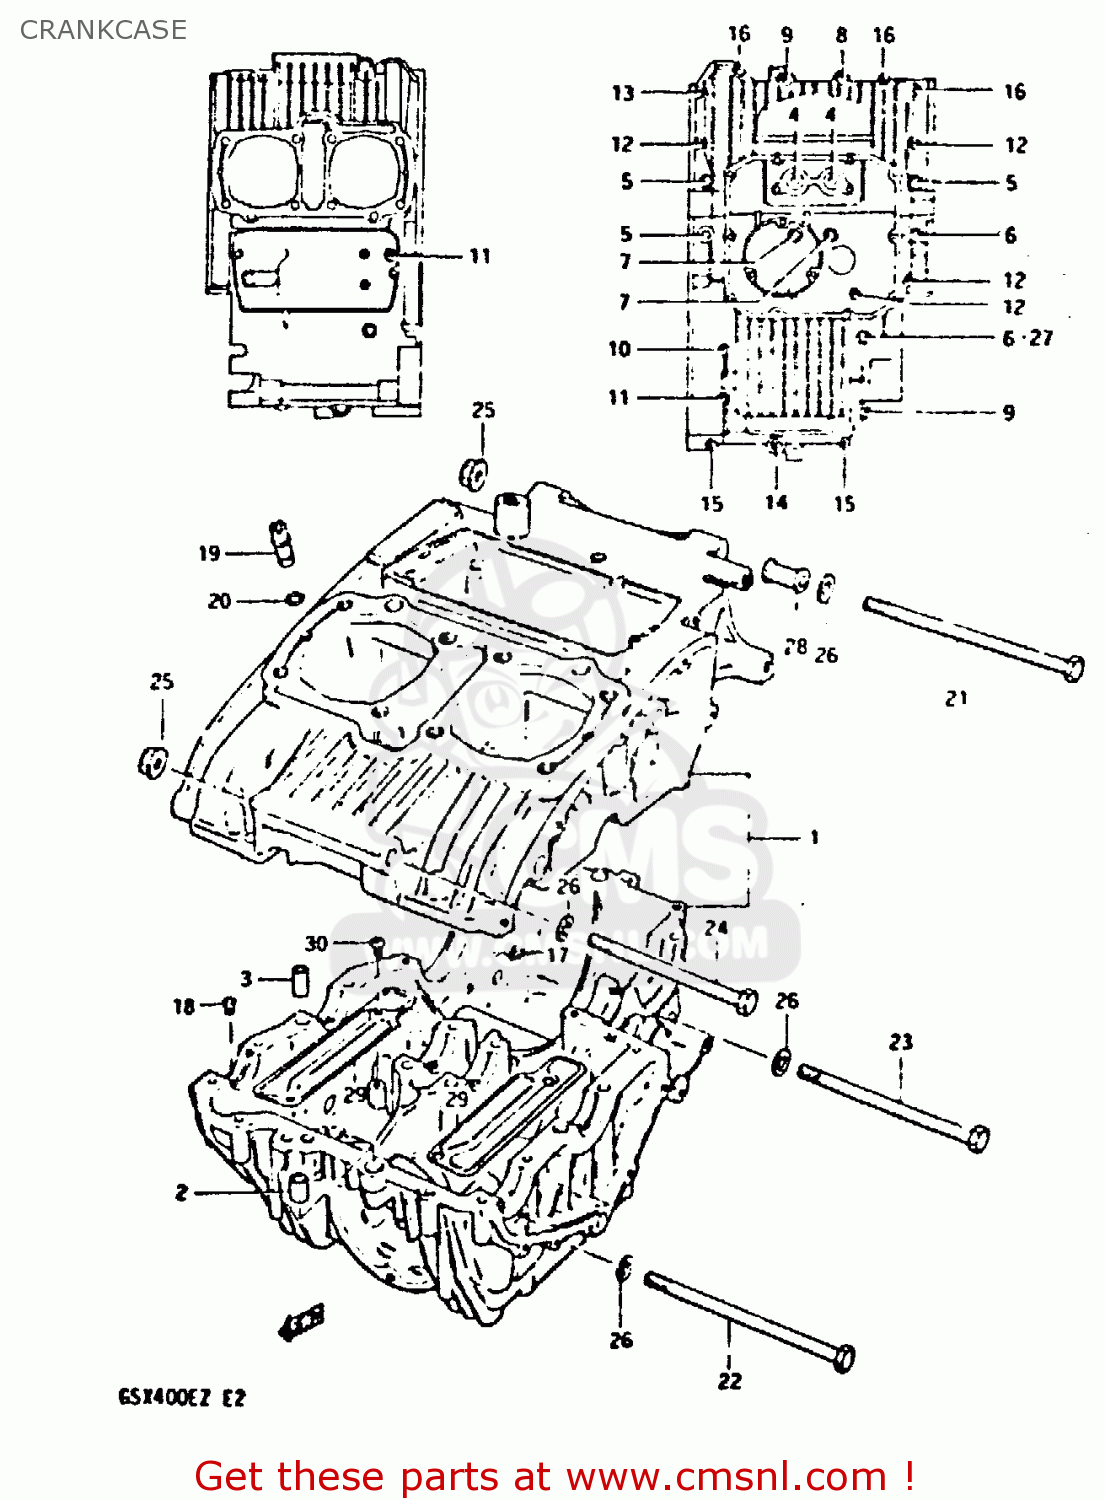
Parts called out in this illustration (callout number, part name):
1	CRANKCASE ASSEMBLY
2	PIN(10.4X13X22)
3	PIN (11X20)(SUS)
4	BOLT
5	BOLT
6	BOLT
7	BOLT
8	BOLT 8X65
9	BOLT (8X45)
10	BOLT(6X125)
11	BOLT
12	BOLT (6X90)
13	BOLT (6X70)
14	BOLT 6X65
15	BOLT ,6X50
16	BOLT,UNDER
17	JET,AIR
18	JET
19	JET
20	O RING(D:1.05,ID:3.1)
21	BOLT 10X215
22	BOLT(10X210)
23	BOLT 10X160
24	BOLT
25	NUT 10MM
26	WASHER
27	GASKET 8.2X14X1 (NAS)
28	SPACER,ENGINE MOUNT
29	PLATE,OIL SEPARATOR
30	SCREW
